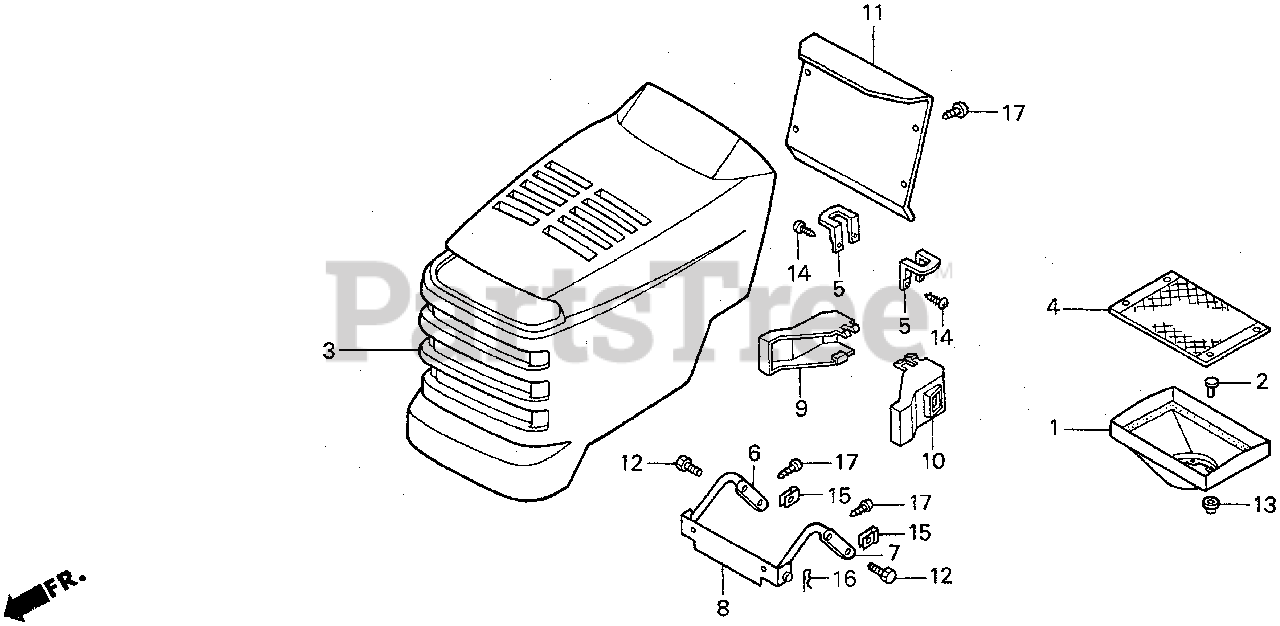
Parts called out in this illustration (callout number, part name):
1	GUIDE, AIR
2	RIVET, SNAP
4	SCREEN, DUST
5	STRIKER, HOOD
6	HINGE, R. HOOD
7	HINGE, L. HOOD
8	HINGE, HOOD (UPPER)
9	PANEL, R. SIDE
10	PANEL, L. SIDE
11	SEPARATOR, FR.
12	BOLT, HEX. (8X20)
13	COLLAR (6X4)
14	SCREW, TAPPING (5X12)
15	NUT, SPECIAL (8MM)
17	SCREW, TAPPING (5X16)
